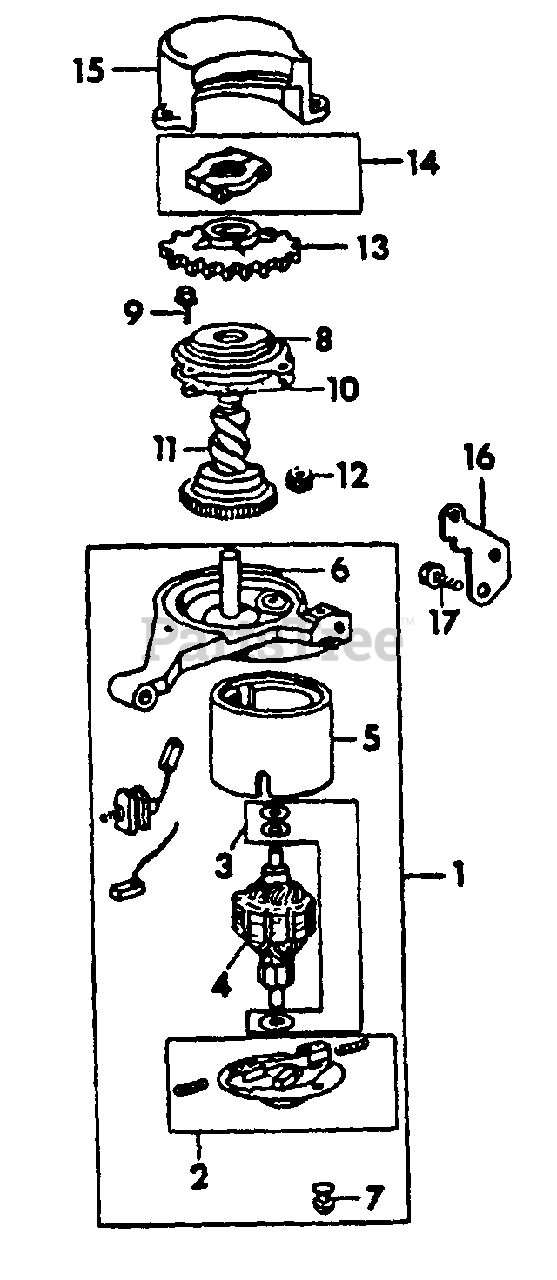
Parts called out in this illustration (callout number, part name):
1	MOTOR ASSY, STARTER
3	WASHER SET, STARTER MOTOR
4	ARMATURE, STARTER
5	HOUSING, STARTER
6	BRACKET, MOTOR OUTPUT - END COVER & MOUNTING
7	SCREW, 10-32 X 3 SLT-RD-HD
8	COVER, ELECTRIC STARTER - CLUTCH GEAR-
9	SCREW, ELECTRIC STARTER CLUTCH GEAR COVER MOUNTING
10	GASKET, ELECTRIC STARTER CLUTCH GEAR COVER
11	CLUTCH, ELECTRIC STARTER
12	GEAR, ELECTRIC STARTER PINION - 12 T
13	GEAR, ELECTRIC STARTER SPUR - 23 T
14	CLAMP, SPUR GEAR RETAINER
15	COVER, ELECTRIC STARTER
16	SUPPORT, ELECTRIC STARTER - MOUNTING BRACKET
17	SCREW, ELECTRIC STARTER - MOUNTING BRACKET
